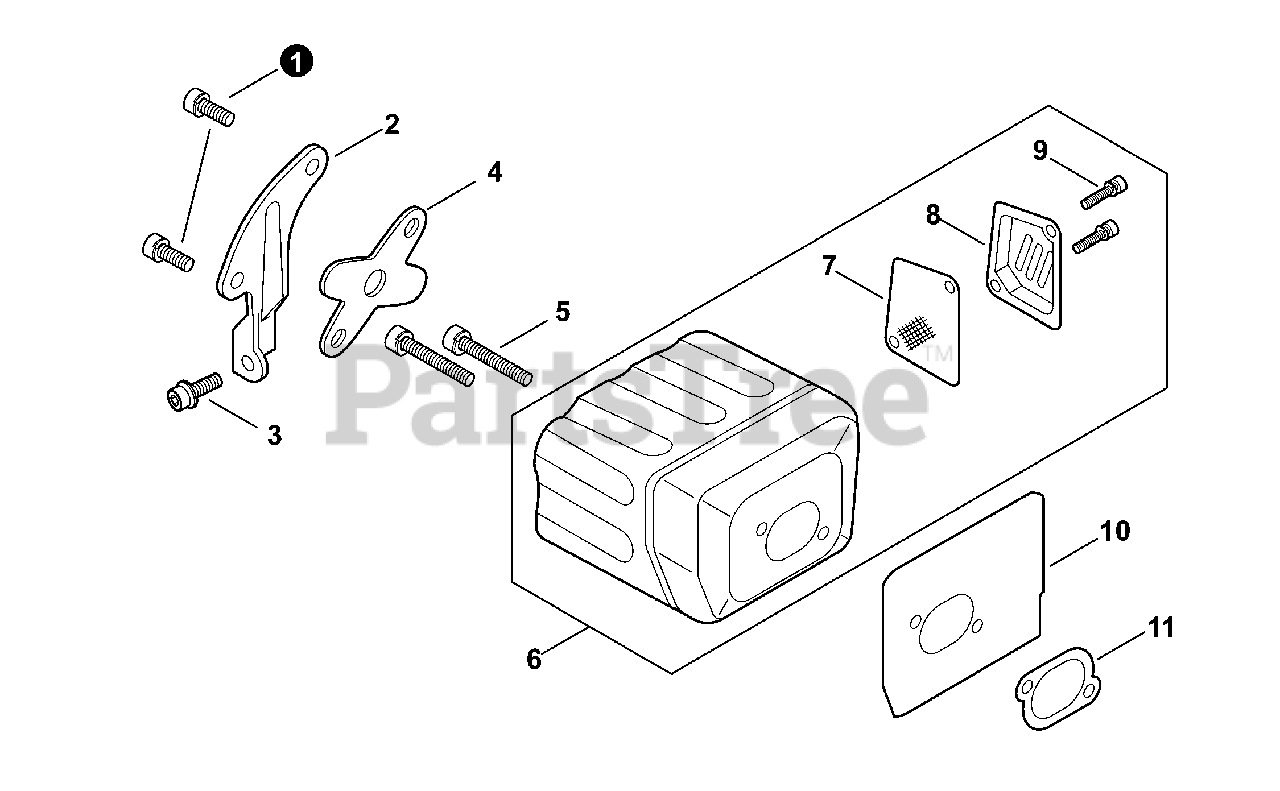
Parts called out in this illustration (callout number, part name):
1	BOLT 5×10
2	BRACKET, MUFFLER
3	BOLT, ADHESIVE M5×20
4	COVER, MUFFLER
5	BOLT 5×20
6	MUFFLER ASSY
7	SCREEN, SPARK ARRESTER
8	GUIDE, EXHAUST
9	BOLT 4×10
10	HEAT SHIELD, EXHAUST
11	GASKET, EXHAUST
